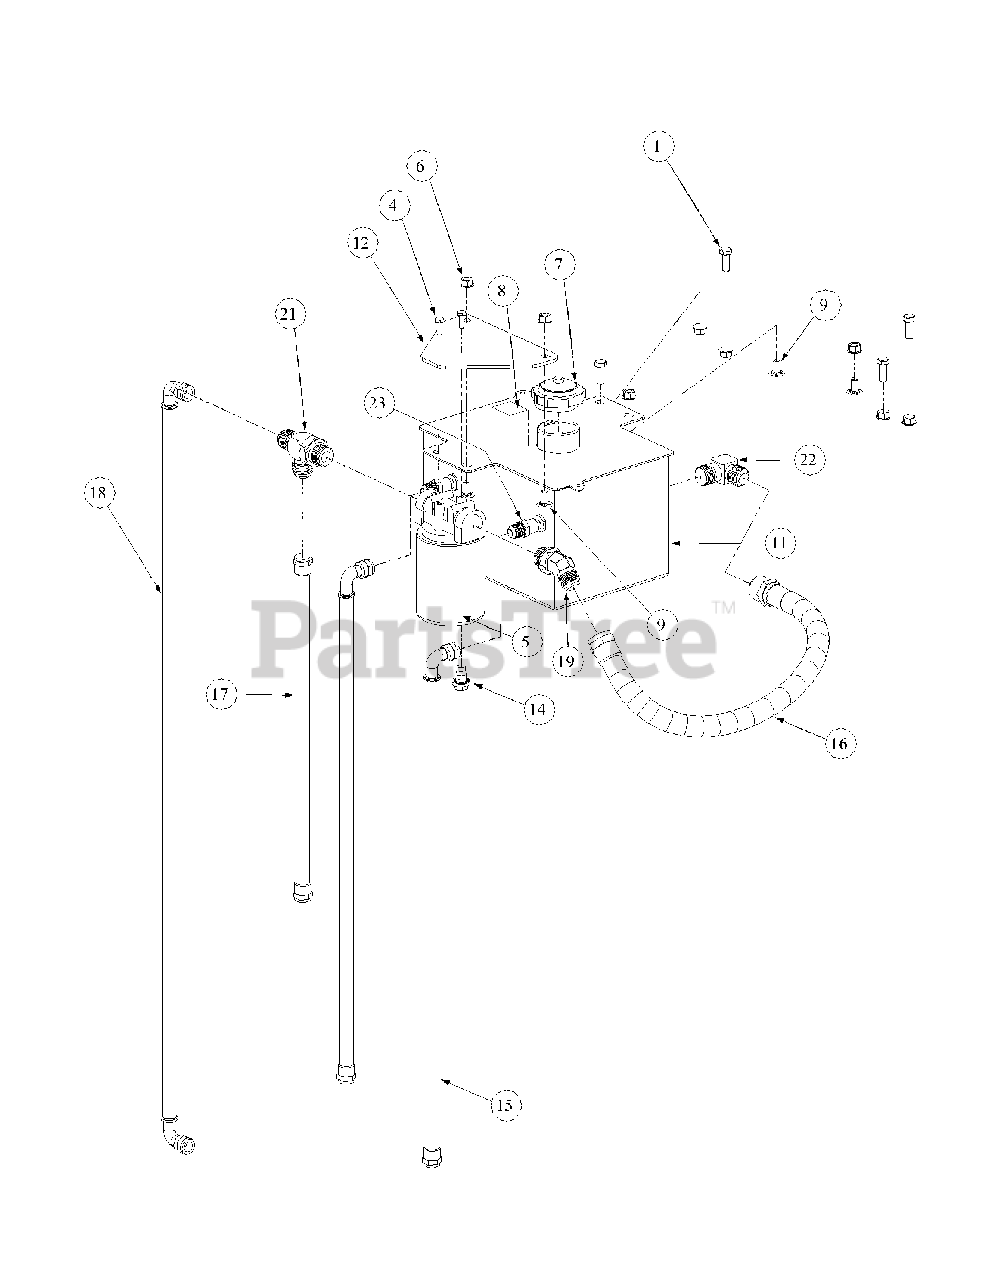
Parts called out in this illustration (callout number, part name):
1	Hex Cap Screw, 3/8-16, 1
3	Protective Hose Cover
4	Hex Cap Screw, 1/4-20, .75
5	Filter Head 3/4
5	33 Micron Filter
6	Hex Nut Flange Lock, 3/8-16
7	Cap, Hydro Oil Tank
8	Decal Oil Only 20W50
9	Carriage Bolt, 3/8-16 x .75 LG.
11	Hydraulic Tank Assembly
12	Mounting Plate Oil Filter
14	Oil Pan Drain w/ Seal and Plug
15	Gearbox to Tank Hose Assembly
16	Tank to Filter Hose Assembly
17	Filter to Left Hand Pump Hose Assembly
18	Filter to Right Hand Pump Hose Assembly
19	Fitting, 45°.
21	Fitting Tee, 3/4 x 1/2 x 1/2
22	Fitting Elbow, 1/2 x 1/2
23	Fitting, 3/8 NPT, 1/2 Flare
